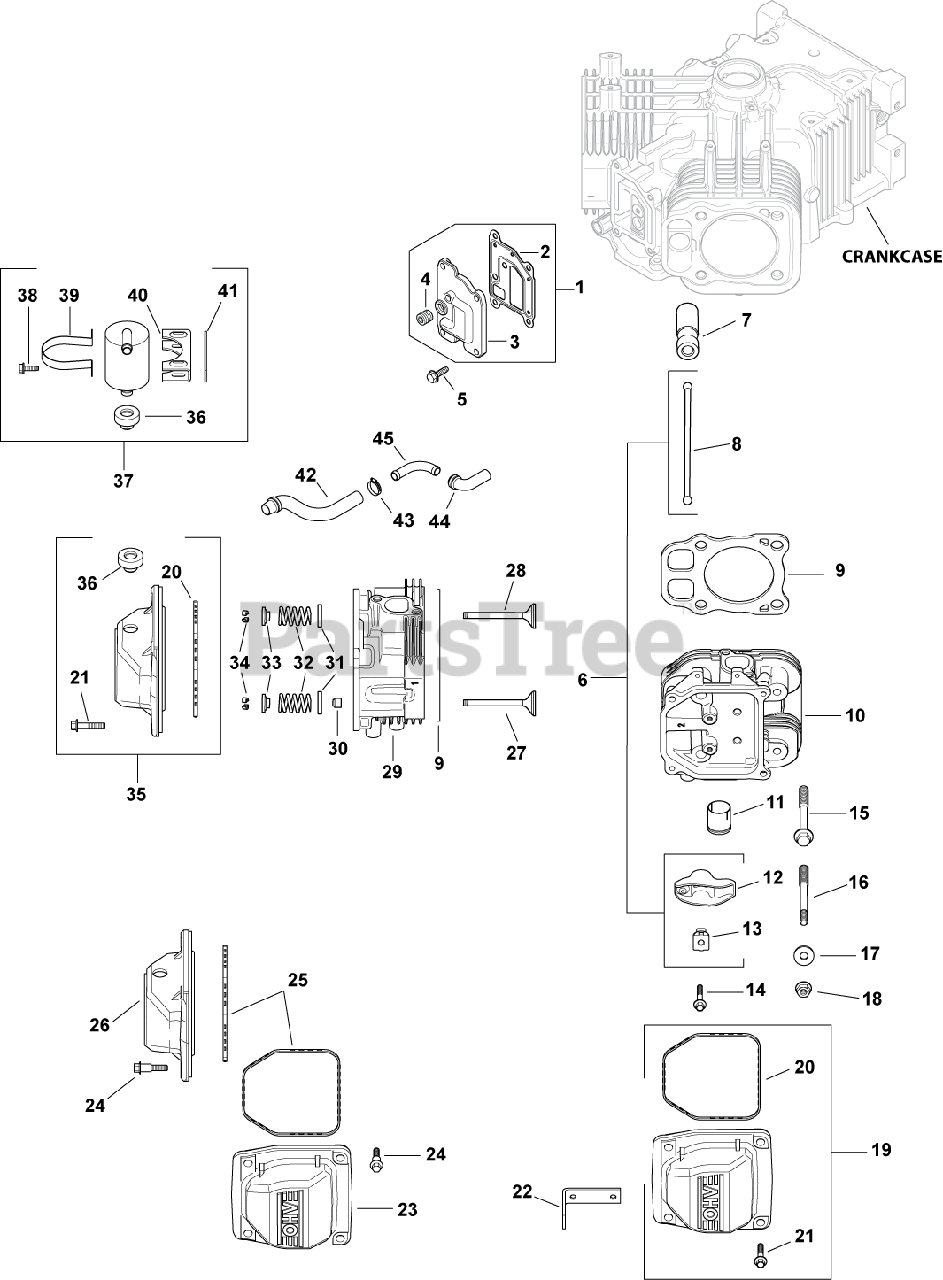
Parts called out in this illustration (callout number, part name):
1	KIT, BREATHER COVER W/GASKET
2	GASKET, BREATHER-USE 24 041 67-S
3	COVER, BREATHER -USE 24 096 125-S
4	PLUG, CTSK PIPE 1/8"
5	SCREW,FLG THD FRM M6X1.0X20-(#25086396S)
6	KIT, VALVE TRAIN
7	LIFTER, HYDRAULIC VALVE-USE 25 351 10-S
8	ROD, PUSH
9	CYL HEAD GASKET KIT-USE 24 841 04-S
11	LINER, EXHAUST PORT-USE 24 605 07-S
12	ARM, ROCKER
13	PIVOT, CYLINDRICAL ROCKER ARM-USE 24 599
14	SCREW, FLG M6X1.0X34
15	SCREW-USE 62 086 08-S
16	STUD, M8X1.25
17	WASHER, FLAT 8.6 MM
18	NUT, FLG M8X1.25
19	KIT, VALVE COVER-PLAIN
20	O-RING (YELLOW) -USE 24 153 30-S
21	SCREW, FLG M6X1.0X30
22	STRAP, LIFTING-USE 25 445 03-S
24	SCREW, SHOULDER
25	O-RING (BLACK)
27	VALVE, EXHAUST (STD) - USE 32 016 01-S
28	VALVE, INTAKE (STD)
31	RETAINER, SPRING
32	SPRING, VALVE
33	RETAINER, VALVE SPRING - USE 25 173 28-S
34	KIT, RETAINER
35	KIT, VALVE COVER
37	KIT, BREATHR SEPARATR-(#24755241S)
38	SCREW,FLG THD FRM M5X0.8X16-(#25086398S)
39	STRAP, BREATHER - USE 24 755 241-S
40	BRACKET, BREATHER SEPARATOR
41	SPACER
42	HOSE, BREATHER-USE 24 326 87-S
43	CLAMP, HOSE (KM)-USE 25 237 31-S
44	HOSE, BREATHER-USE 24 326 86-S
2401602-S	VALVE, EXHAUST (.25)
2401702-S	VALVE, INTAKE (.25)
2431869-S	HEAD, ASSEM CYLINDER #1 -USE 24 318 108-
2431872-S	HEAD, ASSEM CYLINDER #2 -USE 24 318 116-
24755147-S	KIT, CYLINDER HEAD HARDWARE
